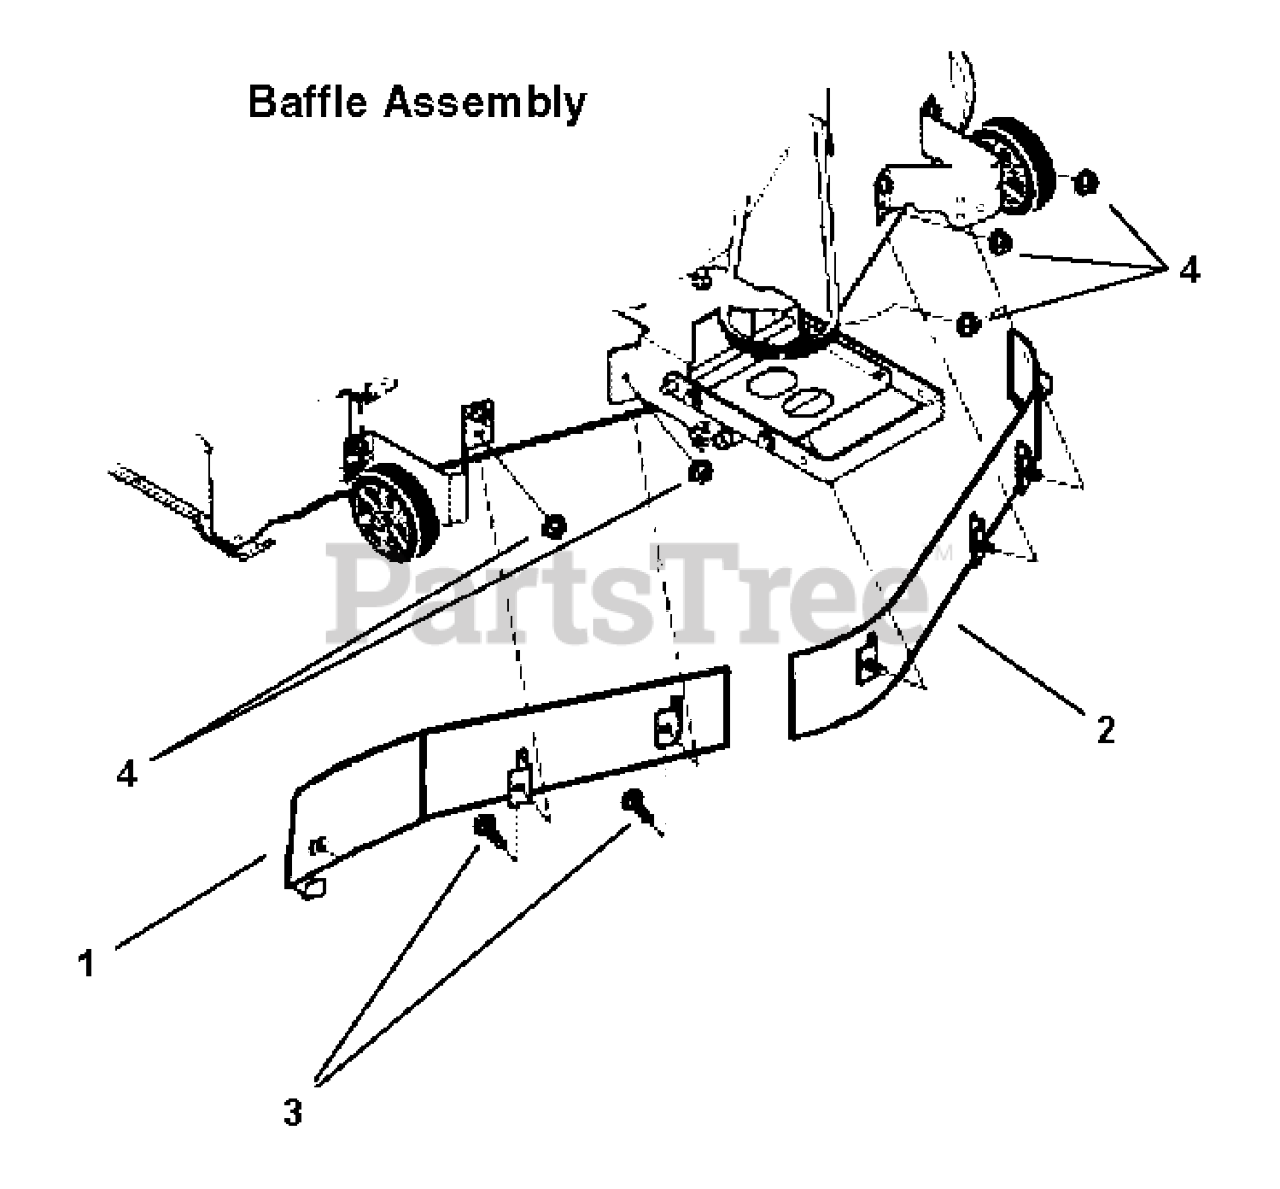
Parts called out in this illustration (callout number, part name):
1	BAFFLE, RIGHT
2	BAFFLE, LEFT
3	BOLT, CARRIAGE, SN, 5/16-18 X 3/4 BLK
3	BOLT, CARRIAGE, SN, 5/16-18 X 1 1/4 GR 5 BLK
4	NUT, HEX FLANGE, 5/16-18
